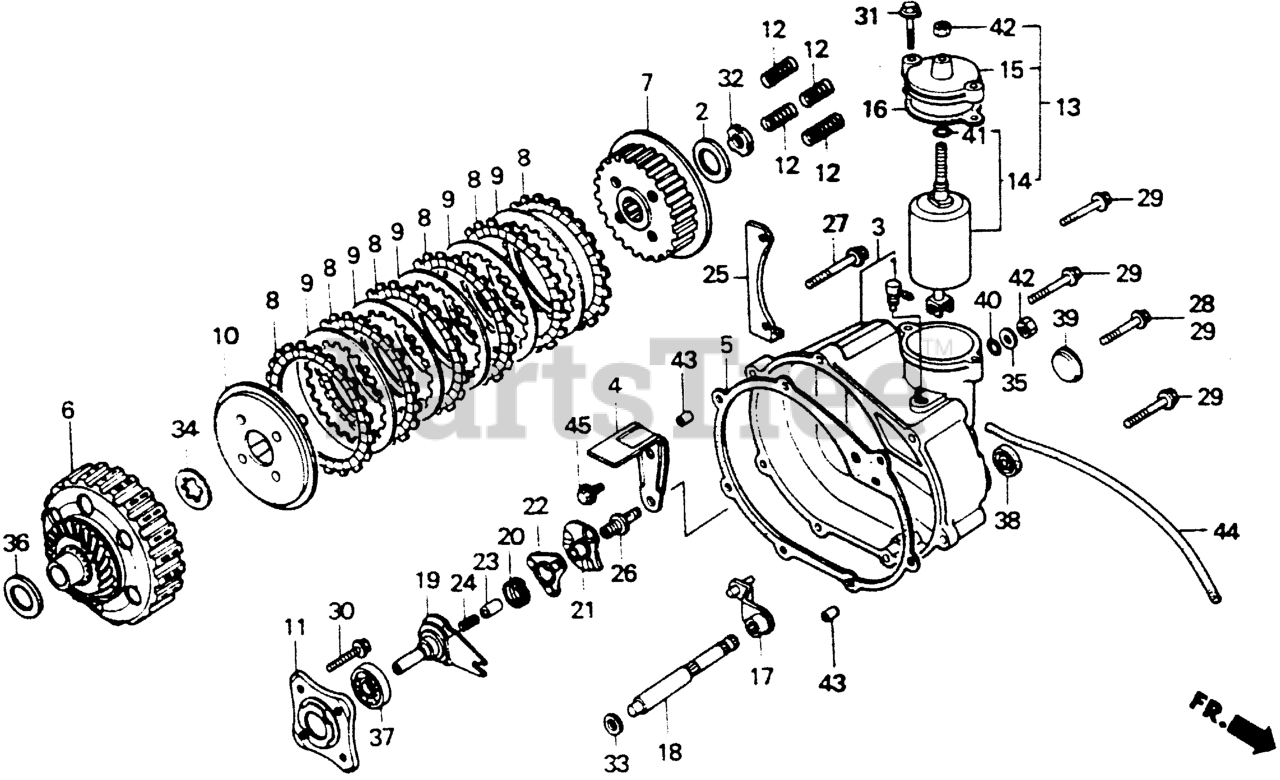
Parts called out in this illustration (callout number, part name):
1	JOINT, BREATHER
2	WASHER, OIL FILTER ROTOR LOCKING
3	COVER, CLUTCH
4	GUIDE, OIL
5	GASKET, CLUTCH COVER
6	CLUTCH (OUTER)
7	CENTER, CLUTCH
8	DISK, CLUTCH FRICTION
9	PLATE, CLUTCH
10	PLATE, CLUTCH PRESSURE
11	PLATE, CLUTCH LIFTER
12	SPRING, CLUTCH
13	DAMPER SET, CLUTCH (N/A: SEE COMPONENTS)
14	DAMPER ASSY., CLUTCH
15	BRACKET, DAMPER (UPPER)
16	GASKET, CLUTCH DAMPER
17	LEVER, CLUTCH
18	SHAFT, CLUTCH
19	PLATE, CLUTCH CAM
20	SPRING, CAM PLATE SIDE
21	PLATE, CLUTCH LIFTER (NOT AVAILABLE)
22	RETAINER, CLUTCH BALL
23	THROUGH, OIL
24	SPRING, OIL THROUGH
25	STAY C, TRANSMISSION
26	BOLT, CLUTCH ADJUSTING
27	BOLT, FLANGE (6X42)
28	BOLT, FLANGE (6X35)
29	BOLT, FLANGE (6X32)
30	BOLT, SPECIAL FLANGE (6X28) (NOT AVAILABLE)
31	BOLT, FLANGE (6X25) Use up to Engine SN 2056819.
32	NUT, LOCK (16MM)
33	WASHER (10MM)
33	WASHER, THRUST (10MM)
34	WASHER, SPLINE (20MM)
35	WASHER (8MM)
36	SHIM, MAINSHAFT (20.2X30X1.25) (A)
36	SHIM, MAINSHAFT (20.2X30X1.30) (B)
36	SHIM, MAINSHAFT (20.2X30X1.35) (C)
36	SHIM, MAINSHAFT (20.2X30X1.40) (D)
36	SHIM, MAINSHAFT (20.2X30X1.45) (E)
36	SHIM, MAINSHAFT (20.2X30X1.50) (F)
36	SHIM, MAINSHAFT (20.2X30X1.55) (G)
36	SHIM, MAINSHAFT (20.2X30X1.60) (H)
36	SHIM, MAINSHAFT (20.2X30X1.65) (I)
36	SHIM, MAINSHAFT (20.2X30X1.70) (J)
36	SHIM, MAINSHAFT (20.2X30X1.75)
37	BEARING, RADIAL BALL (16003)
38	OIL SEAL (10X20X5)
39	SEAL, PLUG (25X7)
40	O-RING (8X1.7) (ARAI)
41	O-RING (6.8X1.9)
42	NUT, HEX. (8MM)
43	PIN A, DOWEL (8X14)
44	BULK HOSE, VACUUM (5X3000) (5X250)
45	BOLT, FLANGE (6X12) Use up to Engine SN 1543277.
